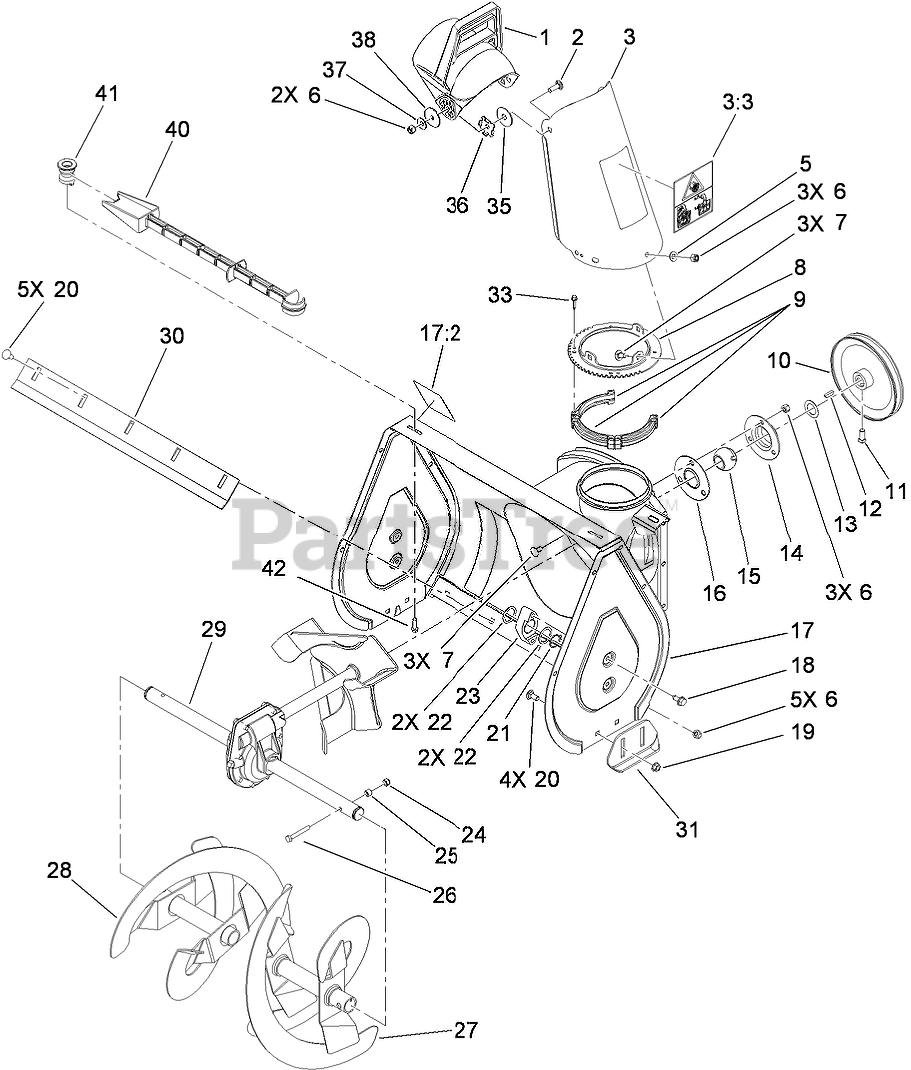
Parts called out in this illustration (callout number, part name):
1	CHUTE-DEFLECTOR
2	SCREW-CARR
3	CHUTE ASM
3:3	DECAL-DANGER, DISCHARGE
5	WASHER-PLAIN
6	NUT-LOCK, NI
7	SCREW-CARR
8	RING-CHUTE
9	RING-CHUTE, RETAINER
10	PULLEY
11	SCREW-SET, SQH
12	KEY-WOODRUFF
13	WASHER
14	FLANGE-CUP, BEARING
15	BEARING-BALL
16	FLANGE-CUP, BEARING
17	AUGER HOUSING ASM
17:2	DECAL-DANGER, AUGER
18	SCREW-HWHTF
19	NUT-HF
20	BOLT-CARR
21	RING-RETAINING
22	WASHER
23	BEARING-AUGER
24	NUT-LOCK, NI
25	SPACER
26	SCREW-HH
27	AUGER-LH
28	AUGER-RH
29	22 INCH GEAR CASE ASM
30	BLADE-SCRAPER
33	SCREW-SPECIAL
35	WASHER-RUBBER
36	PLATE-FRICTION
37	WASHER-BELLEVILLE
38	WASHER-FLAT
40	STICK-CLEANOUT
41	HOLDER-STICK
42	SCREW-HWH
